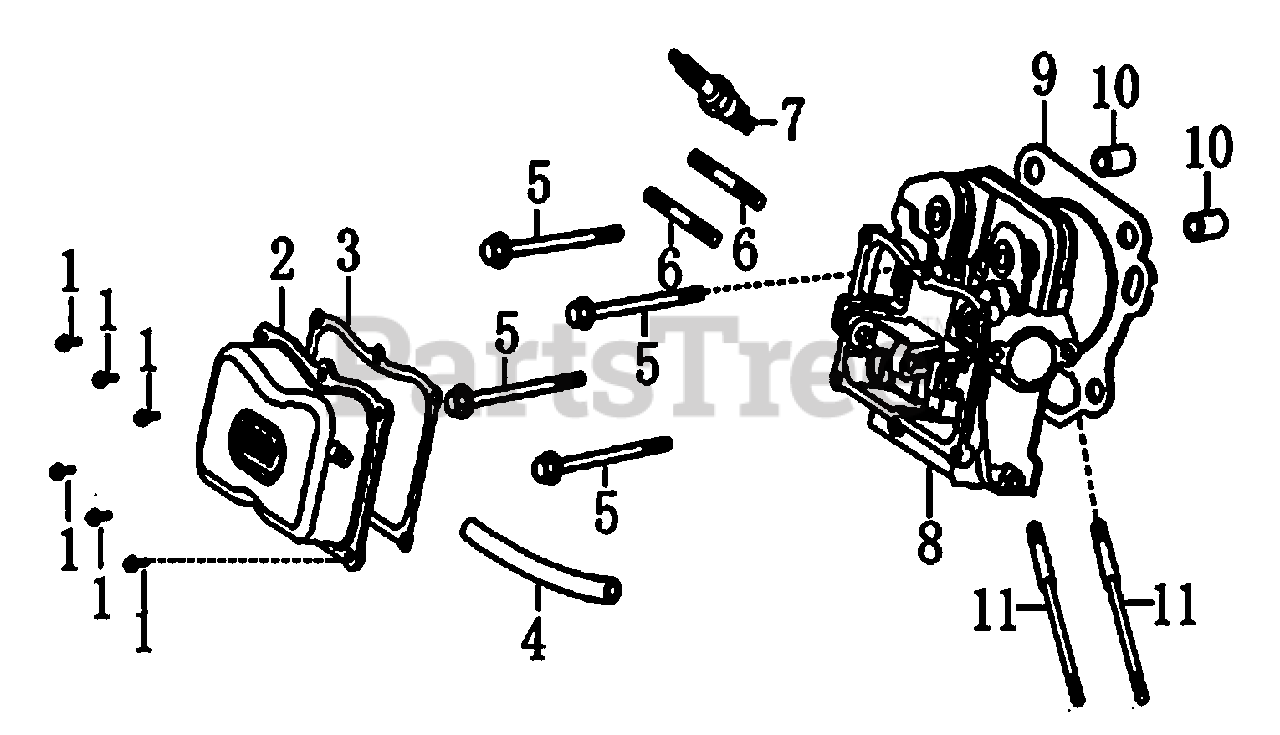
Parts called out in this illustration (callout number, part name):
1	BOLT, FLANGE
2	COVER, HEAD
3	GASKET, HEAD COVER
4	TUBE, BREATHER
5	BOLT, HEAD, 10X80
6	BOLT, STUD, EXHAUST
7	SPARK PLUG
8	HEAD, CYLINDER
9	GASKET, CYLINDER HEAD
10	PIN, DOWEL
11	BOLT, STUD, INTAKE
